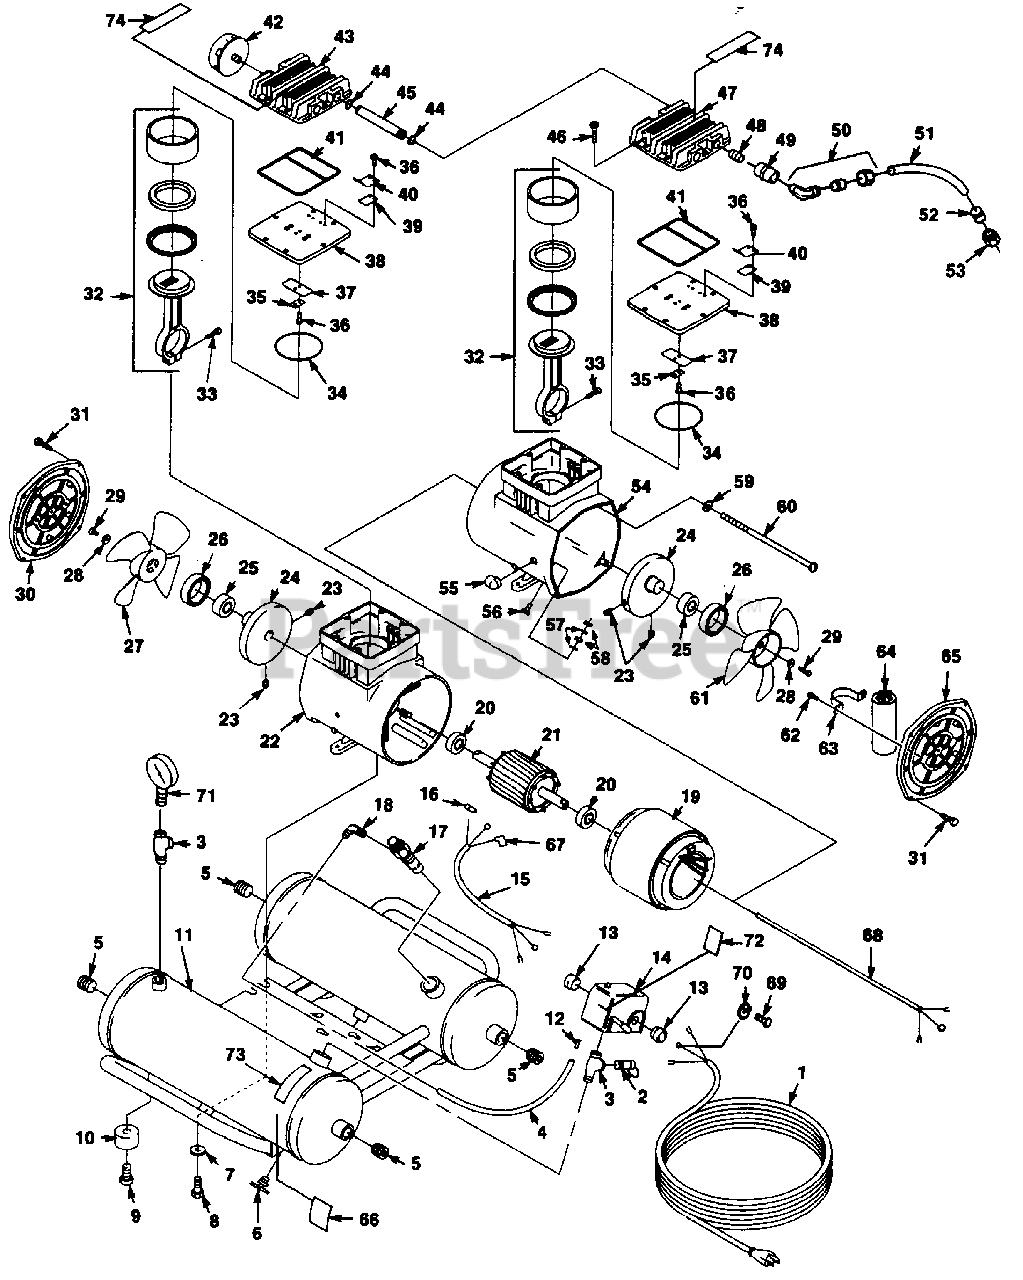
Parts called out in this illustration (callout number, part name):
7	WASHER, LOCK
8	SCREW-Mach Hex Hd.(1/4-20 X 1/2")
9	SCREW TBO
33	HEX SCREW
37	VALVE FLAPPER
